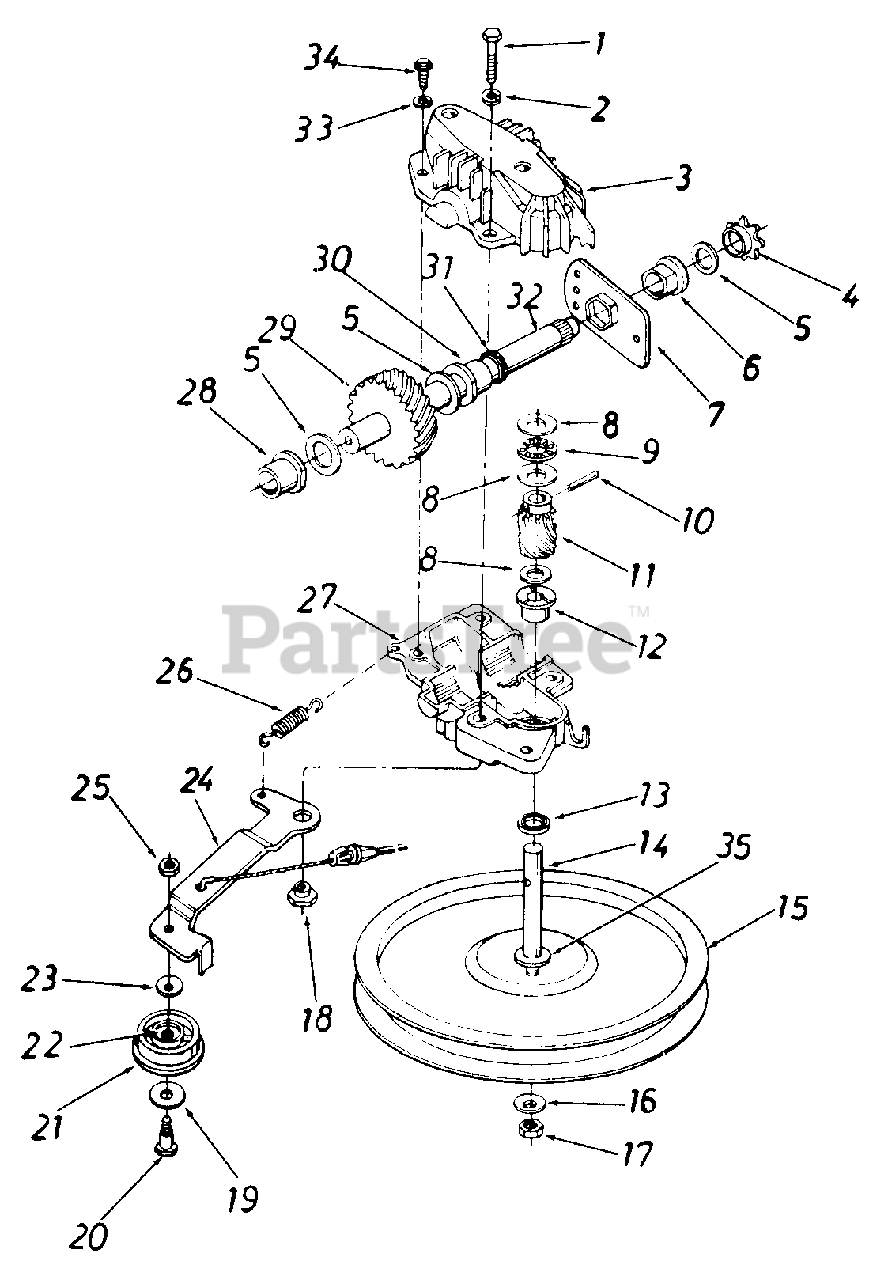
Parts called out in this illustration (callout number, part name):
1	Hex Bolt 1/4-20 x 1.25" Lg.
2	L-Wash. 1/4" I.D.
3	Upper Hsg. Half
4	#48 Sprocket 7 Tooth x 1/2 Pitch
5	Fl-Wash. 5/8" I.D. x .030
6	Hex Flange Brg. 631" I.D.
7	Hex Bearing Cup
8	Thrust Wash. .382" I.D. x 70n 0 D
9	Thrust Bearing .375" I.D. x-.812" O.D.
10	Spring Pin Spir. 1/8" x .62" Heavy
11	11 Tooth Helical Gear
12	Flange Bearing
13	Oil Seal
14	Pulley-Transmission Shaft
15	Fl-Pulley 5.06" O.D.
16	Bell-Wash. .265" I.D. x 75"
17	Hex L-Nut 1/4-28 L.H. Thd.
18	Shld. Spacer .375" Dia. x .1 70
19	Fl-Wash. .390" I.D. x 1.0"
20	Shld. Bolt .375" Dia. x .40"
21	Fl-Idler Plastic 1.50" Dia.
22	Needle Brg. .375" x .31
23	Bell-Wash. .265" I.D. x 75"
24	Idler Brk't. Ass y
25	Hex Patch L-Nut 1/4-28 Thd.
26	Extension Spring 1.12" Lg.
27	Lower Hsg. Half
28	Flange Bearing .566 Dia.
29	33 Tooth Helical Gear
30	Flange Bearing .629 Dia.
31	Oil Seal .625 Dia.
32	Gear Sprocket Shaft
33	L-Wash. #10 I.D.
34	Hex B-Tap Scr. #10 x .62"
35	Hex Washer .26" x .88"
